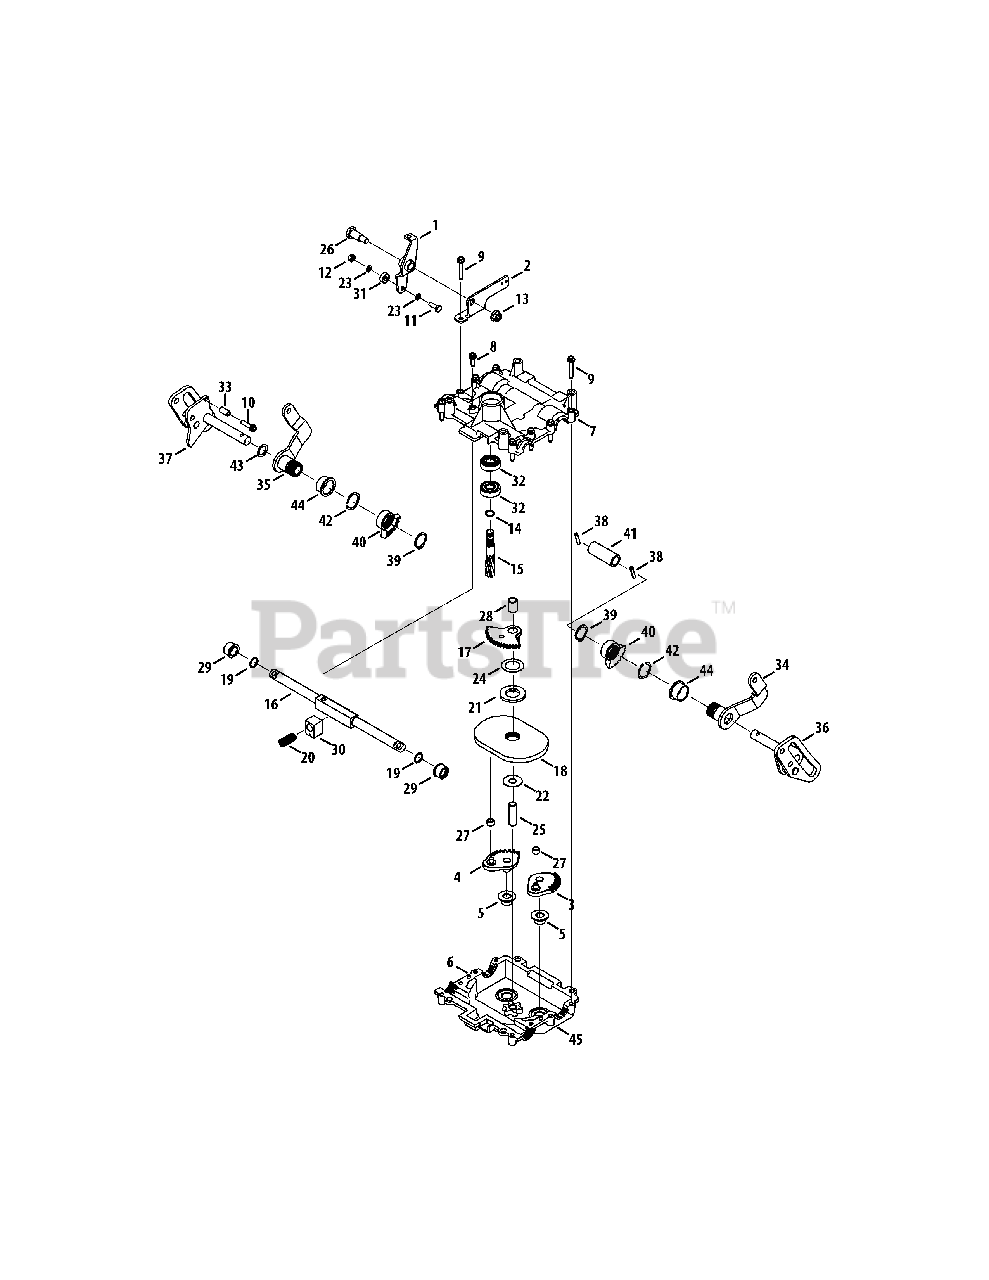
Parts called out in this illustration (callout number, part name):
1	Cam Plate Assembly
2	Neutral Bracket
3	LH Steering Gear Assembly
4	RH Steering Gear Assembly
5	Flange Bearing, .5 x .700
6	Dowel Pin, 3/16 x 1/2
7	Upper Steering Housing
8	Hex Washer Screw, 1/4-20 x 0.750
9	Hex Washer Screw, 1/4-20 x 1.500
10	Hex Washer Screw. 1/4-20 x 1.000
11	Hex Screw, 1/4-20 x .75
12	Flange Lock Nut, 1/4-20
13	Flange Lock Nut, 3/8-16
14	Retaining Ring, .56
15	Pinion Gear, 7-Tooth
16	Synchro Rack Gear
17	Steering Gear, 53-Tooth
18	Hydro Steering Cam
19	O-Ring, .625 x .07
20	Compression Spring, .531 x 1.25
21	Flat Washer, 1.01 x 1.75 x .172
22	Flat Washer, .508 x 1.325 x .040
23	Flat Washer, .260 x .455 x .048
24	Thrust Washer, 1.007 x 1.542 x .03
25	Steering Shaft
26	Shoulder Screw, 3/8-16 x .500 x .835
27	Sleeve Bearing, .437 x .3425
28	Sleeve Bearing, .623 x .5025 x .800
29	Flange Bearing, .625 x .875
30	Rack Caster Bearing
31	Ball Bearing, .25 x .6875 x .25
32	Ball Bearing, .5625 x 1.375 x .4375
33	Spacer, .260 x .375 x .75
34	Steering Arm Asm, Lh, Hydro, Vert
35	Steering Arm Asm, Rh, Hydro, Vert
36	Cam Asm, Lh, Painted
37	Cam Asm, Rh, Painted
38	Pin, Spirol, 3/16 X 1.00, Hd
39	Ring, Snap, 1.0 Dia Shaft
40	Gear, Steering, 26t
41	Tube, Cam, Speed
42	Spring, Wave, M, 24.22x32x1.98, Gap
43	Washer, Flat, .635x.930x.033, Ht
44	Bearing, Sleeve, 1.2 Od X 1.00 Id
45	Lower Steering Housing
